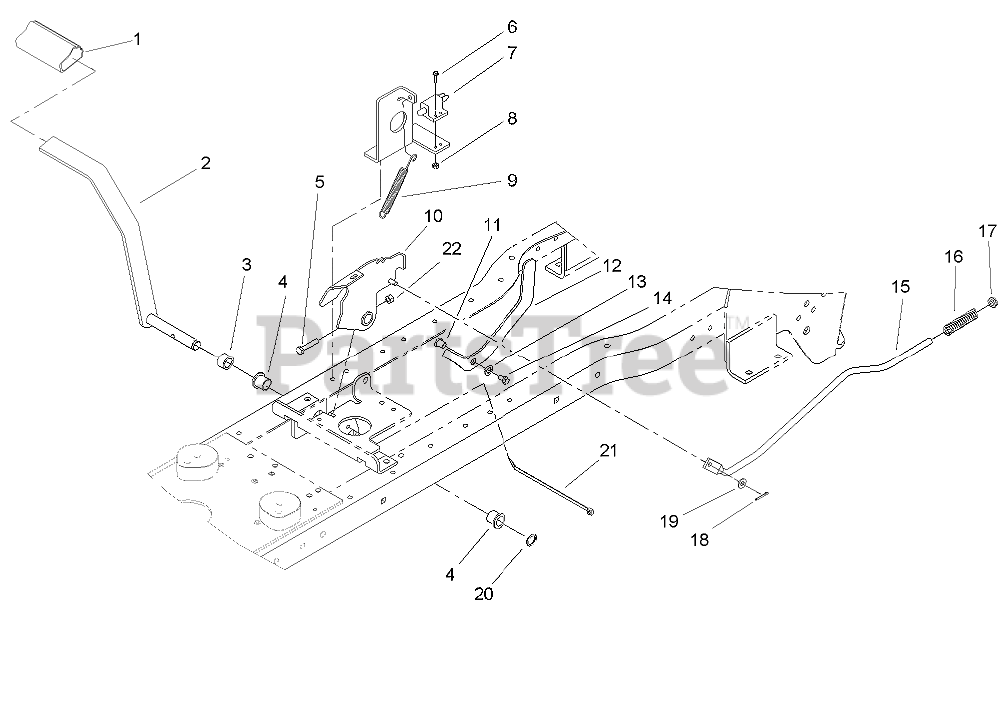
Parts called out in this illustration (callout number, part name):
1	PAD-PEDAL
2	BRAKE PEDAL ASM
3	SPACER-BRAKE
4	BUSHING-FLANGE
5	SCREW-HH
6	SCREW-SHH
7	SWITCH-INTERLOCK
8	NUT-LOCK
9	SPRING-EXTENSION
10	Brake ASM
11	POST-MOUNTING, LINKAGE
12	Lever-Brake, Parking
13	SPACER-BRAKE, PARKING
14	SCREW-HHF
15	ROD-BRAKE
16	SPRING-COMPRESSION
17	NUT-HEX
18	PIN-COTTER
19	WASHER-FLAT
20	RING-RETAINING
21	TIE-CABLE
22	NUT-LOCK, NI
